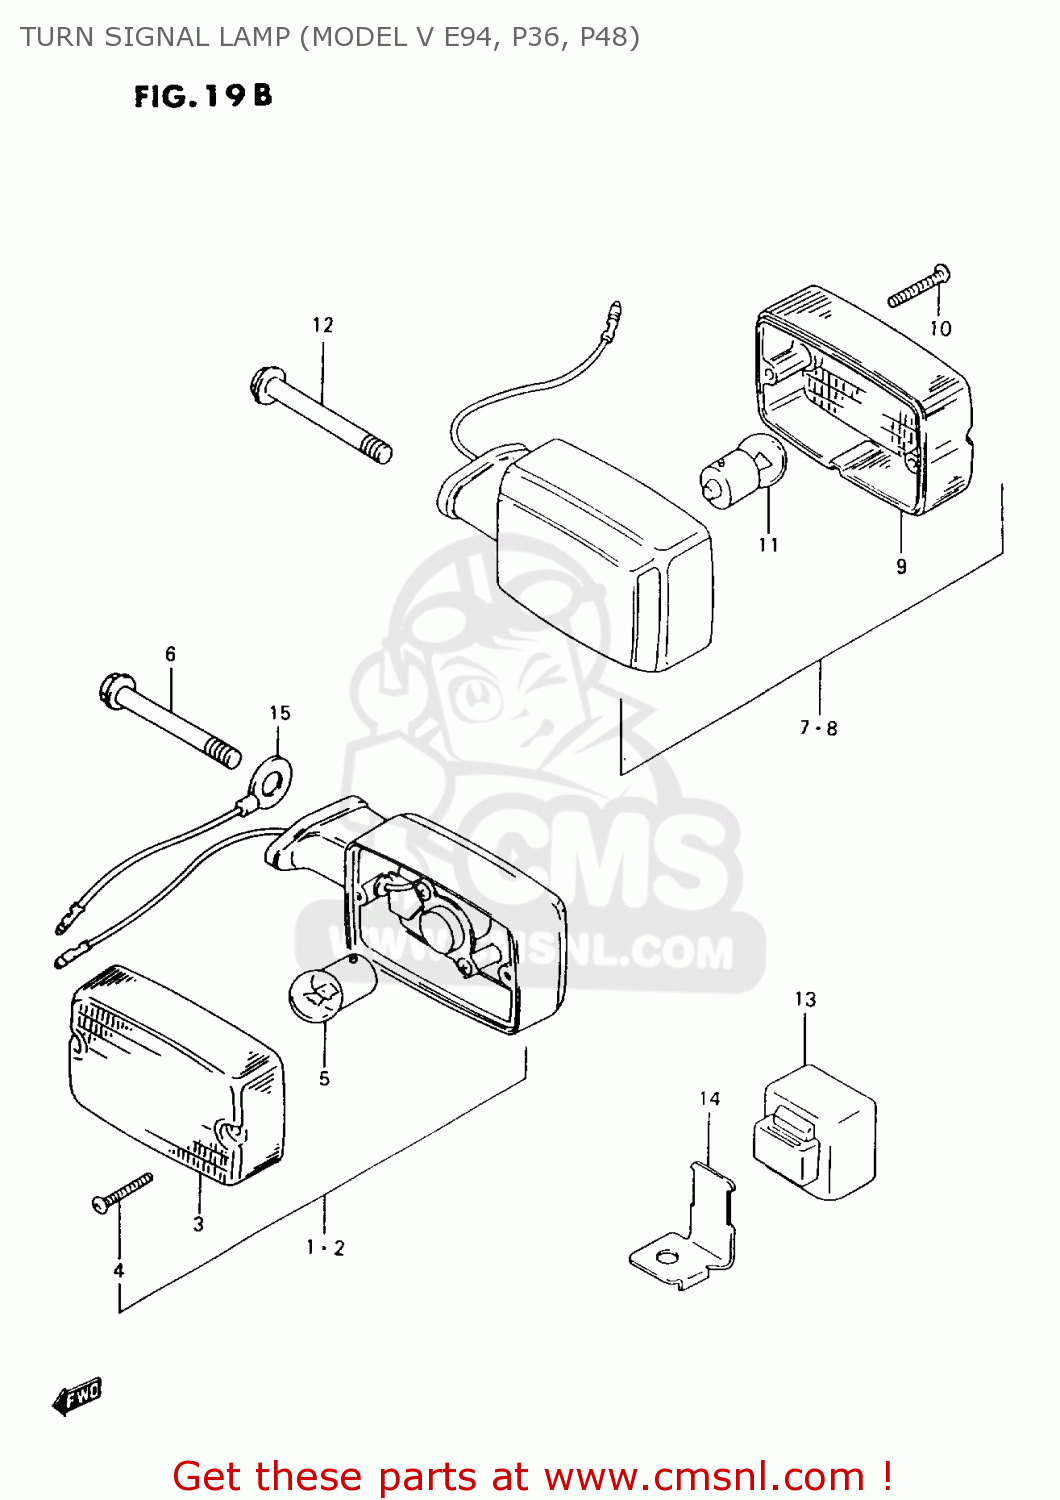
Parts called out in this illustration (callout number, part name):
1	LAMP ASSY, FRONT TURNSIGNAL RH
2	LAMP ASSY, FRONT TURNSIGNAL LH
3	LENS
4	SCREW
5	BULB(6V8W,STANLEY,A4115)
6	BOLT 6X25
7	LAMP ASSY,RR TURNSIGNAL
8	LAMP ASSY,RR TURNSIGNAL,L
9	LENS
10	SCREW
11	BULB(6V8W,STANLEY,A4115)
12	BOLT(6X60)
13	RELAY,TURN SIGNAL
14	BRACKET,TURN SIGNAL RELAY
15	LEAD WIRE,EARTH
